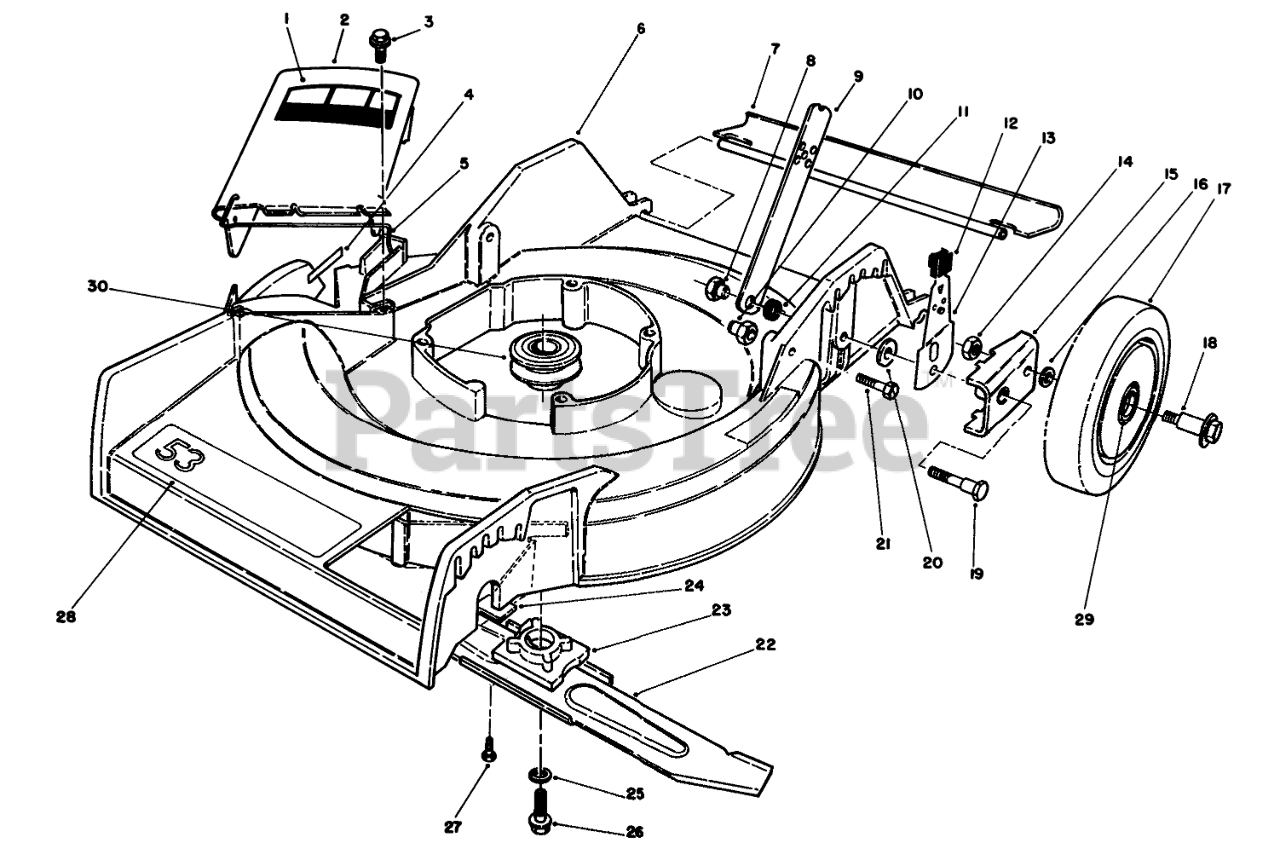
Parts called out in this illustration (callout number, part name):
1	DECAL - DANGER DEFL
2	Deflector (Incl. Ref. #1 & 5)
3	SCREW-HWH
4	DANGER DECAL
5	SPRING HINGE
6	HOUSING W/DECAL
7	SHIELD - TRAILING
8	HANDLE PIVOT NUT
9	HANDLE LATCH
10	HANDLE PIVOT NUT
11	SPACER
12	KNOB-ARM
13	SPRING ARM ASSEMBLY
14	Nut
15	HP PIVOT ARM ASM
16	WASHER
17	Wheel & Tire Assembly (Incl. Ref. #18)
18	BOLT-WHEEL
19	PIVOT SCREW
20	PIVOT WASHER
21	SCREW-HH
22	Blade
23	BLADE RETAINER
24	FRONT SHIELD
25	WASHER-LOCK
26	SCREW-HH
27	SCREW-HWHTF
28	DECAL - SP DECK
29	BUSHING
30	PULLEY-DRIVER
